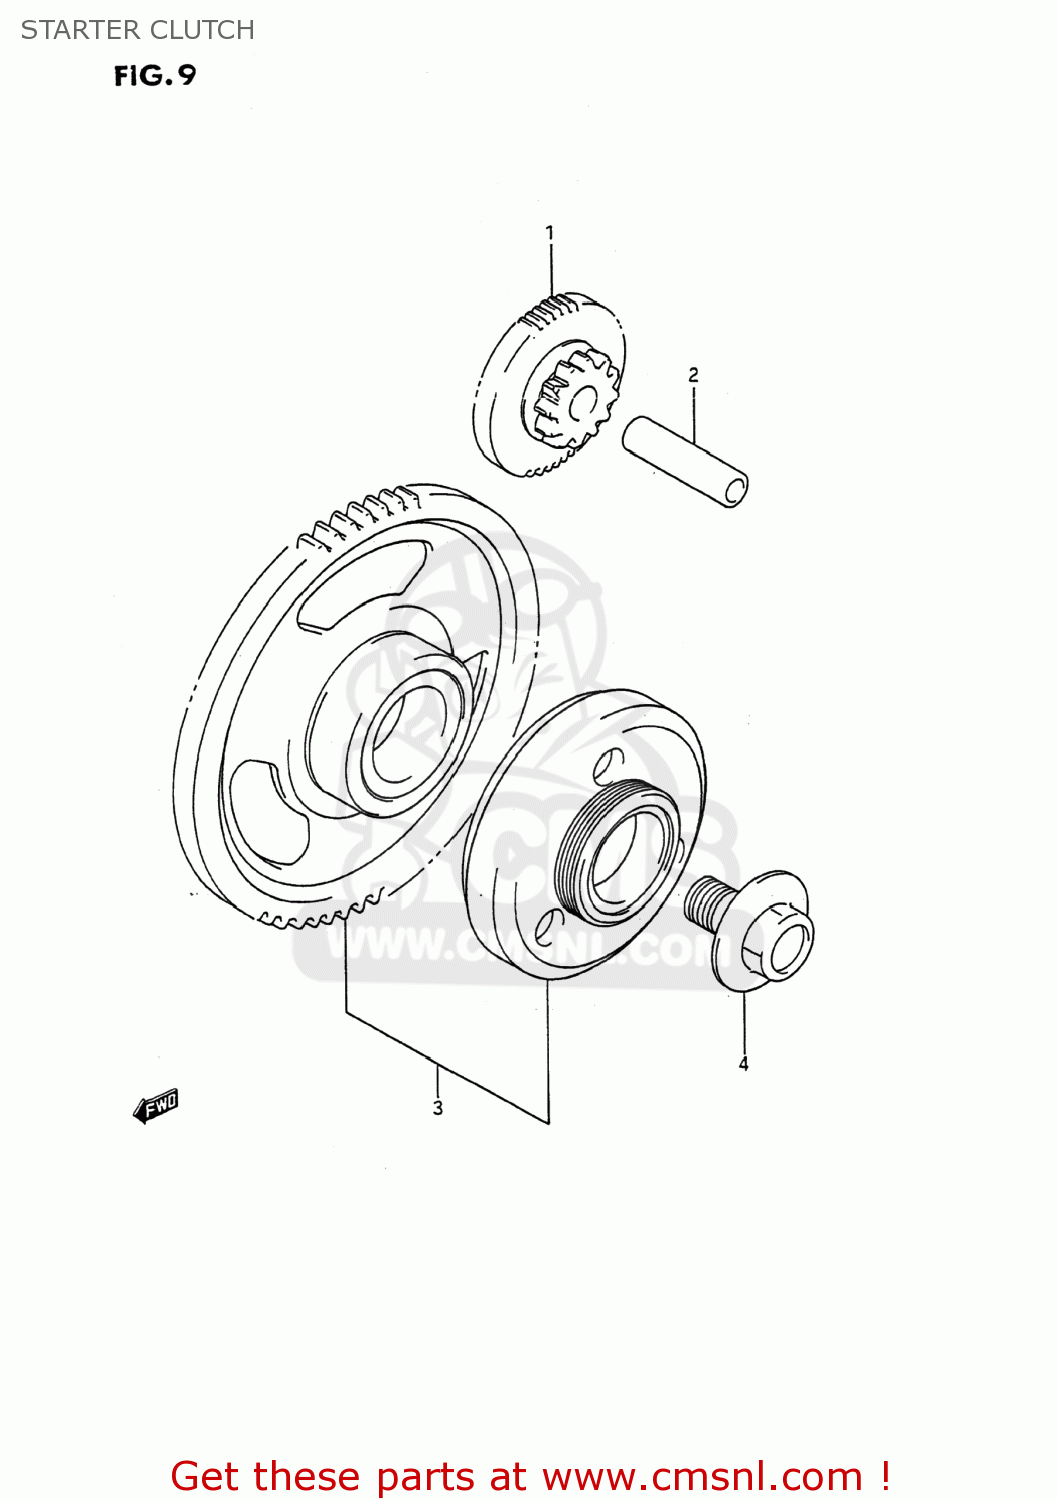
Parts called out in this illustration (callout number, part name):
1	GEAR,STARTER IDLE(NT:12,53)
2	PIN(7X11X42)
3	CLUTCH SET,STARTER
4	BOLT(14X21)
